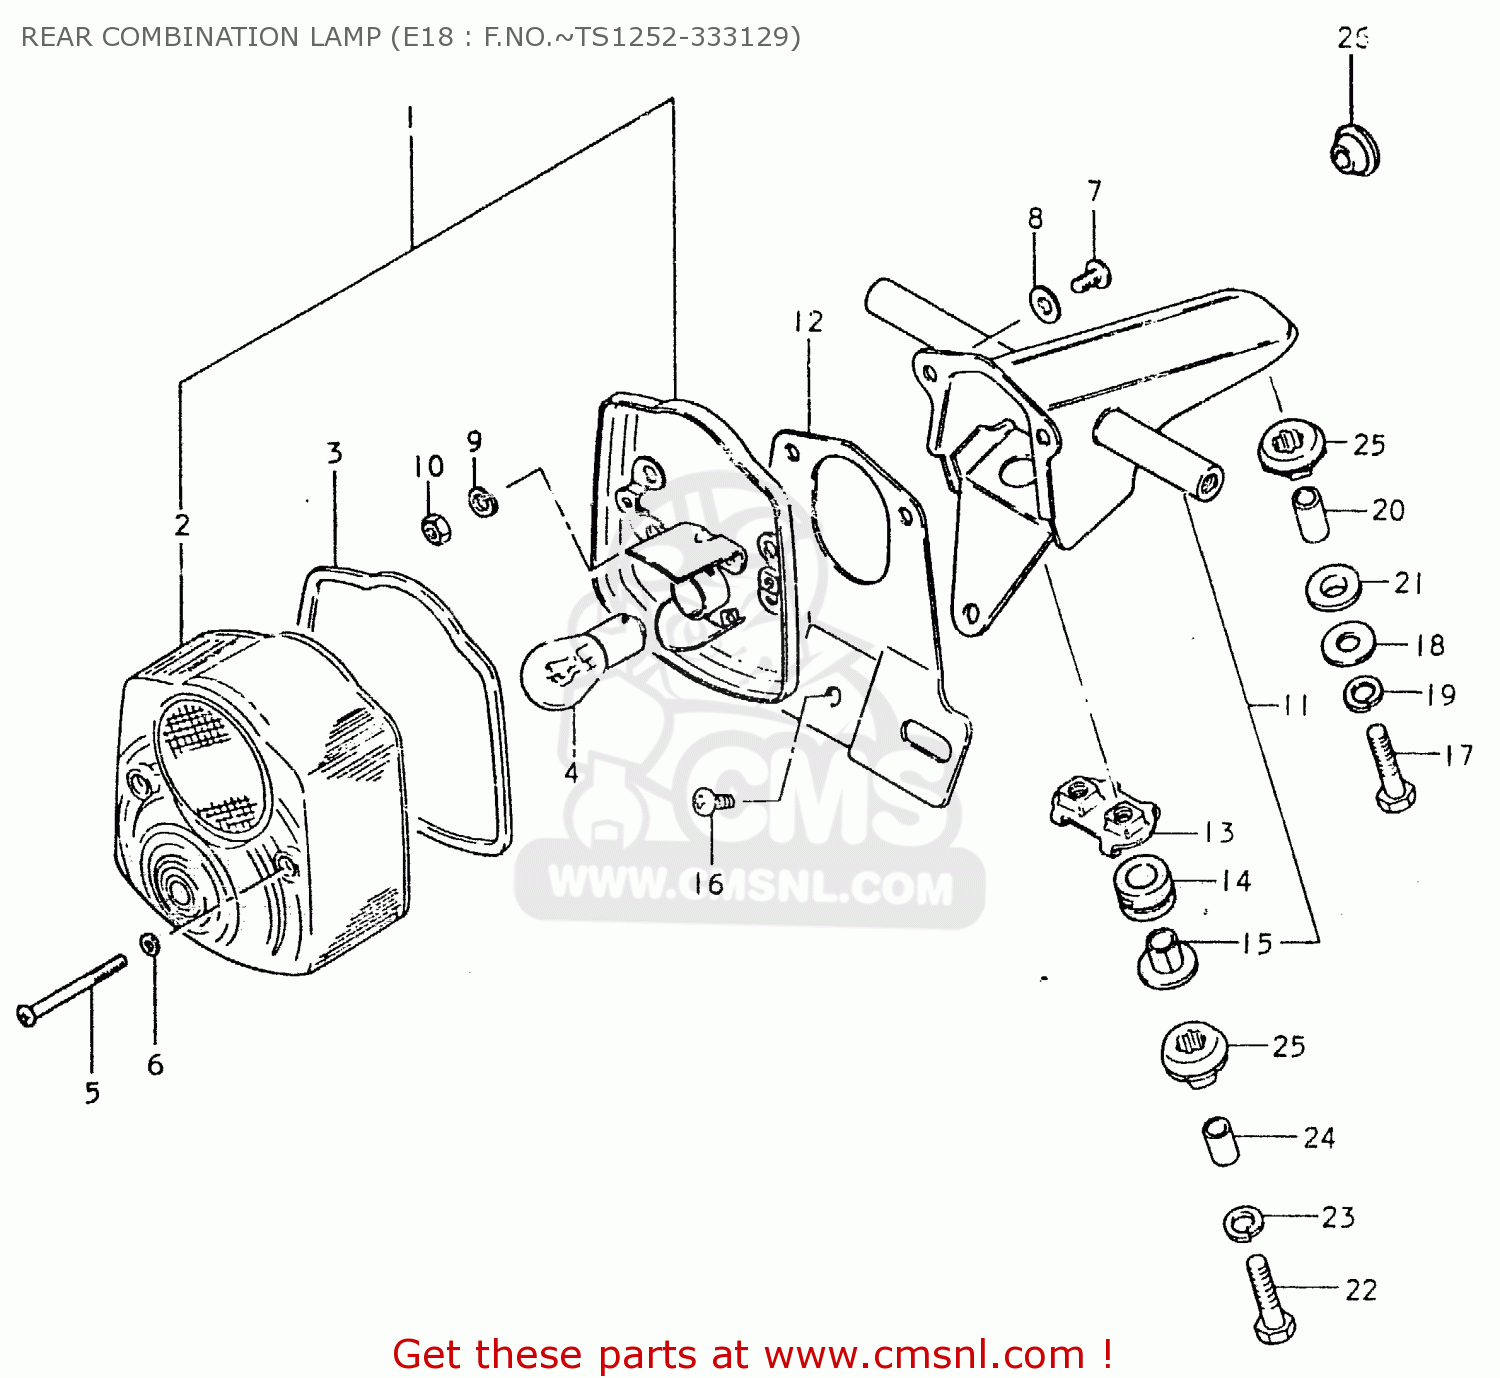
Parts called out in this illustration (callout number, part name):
1	LAMP UNIT, TAIL
2	LENS
3	GASKET (NAS)
4	BULB (6V,21/5W)
5	SCREW
6	GASKET (NAS)
7	SCREW
8	WASHER
9	LOCK WASHER
10	NUT
11	BRACKET ASSY
12	PLATE, LICENSE
13	PLATE
14	CUSHION
15	SPACER
16	SCREW
17	BOLT
18	WASHER (6.5X20X1.2)
19	LOCK WASHER
20	SPACER
21	CUSHION
22	BOLT 6X40
23	LOCK WASHER
24	SPACER (6.8X10X11.5)
25	CUSHION
26	GROMMET
